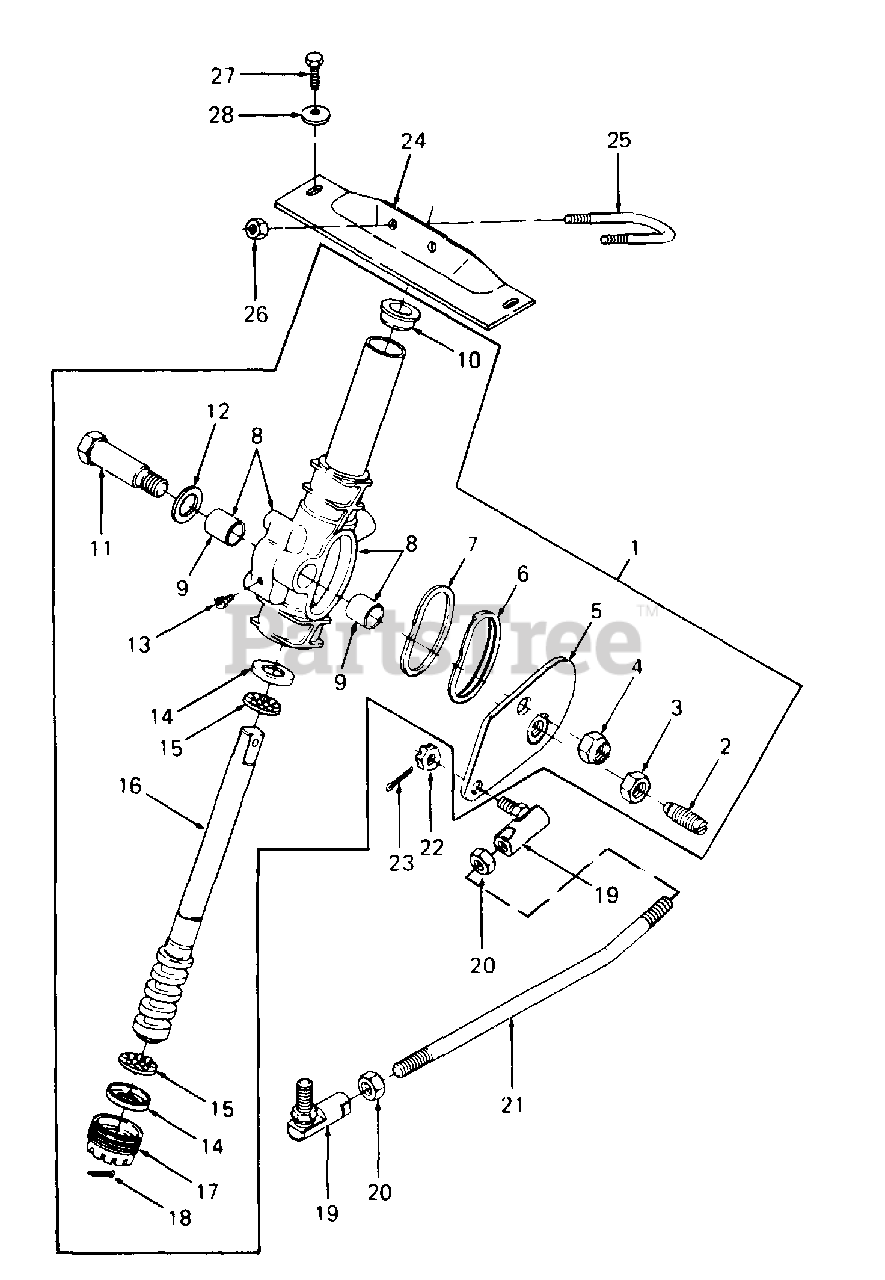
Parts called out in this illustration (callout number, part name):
1	Steering Gear Assy
2	Follower, Cam
3	Nut, Hex Jam, 9/16-18
4	Nut, Hex Crown Lock, 5/8-18
5	Arm, Steering
6	Retainer, Seal
7	Seal
8	Housing/Tube Assy
10	Bearing, Column
11	Shaft, Pivot
12	Washer, Flat, .781 X 1.25 X .027 Thk
13	Fitting, Lube, 45 Deg 1/4-28 Taper
14	Cup, Bearing
15	Retainer Assy, Ball
16	Shaft/Cam Assy
17	Plug, Adjusting
18	Pin, Cotter, 1/8 Dia X .75 Lg
19	Ball Joint
20	Nut, Hex Jam, 1/2-20 GR5
21	Link, Drag
22	Nut, Hex Castle, 1/2-20 GR5
23	Pin, Cotter, 3/32 Dia X 1.25 Lg
24	Plate, Steering Support
26	Nut, Hex Center Lock, 5/16-24
27	Screw, Hex Hd Cutting, 5/16-18 X .75 Lg GR5
28	Washer, Bell, .345 X .88 X 060 Thk
